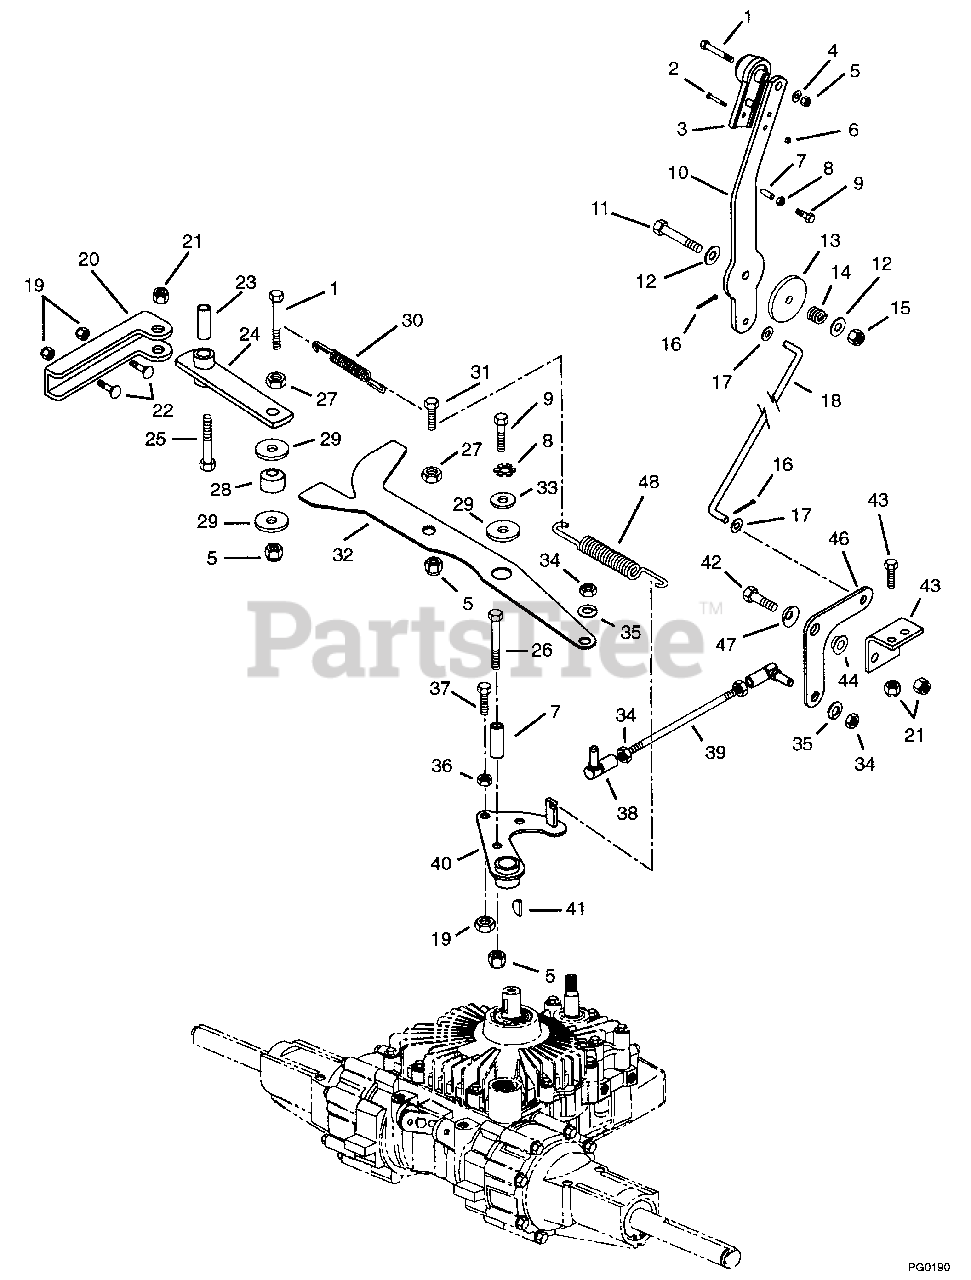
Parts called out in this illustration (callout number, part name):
1	Bolt-Hex .25-20 x 1.50 Grade 5
2	Screw-Machine 6-32 x .625
4	Washer-Flat-Steel .281 x .62 x .065
5	Nut-Locking-Nylon .250-20
6	Nut-Locking-Machine 6-32
7	Bushing-Sleeve .250 x .375 x .640
8	Washer-Lock External .313 x .030
9	Bolt-Hex .25-20 x .75 Grade 5
10	Lever, Speed Control
11	Bolt-Hex .50-13 x 2.50 Grade 5
12	Washer-Flat-Steel .531 x 1.062 x .095
13	Disc, Friction Material
14	Spring-Compression .125 x .78 x 1.00
15	Nut-Locking-Nylon .50-13
16	Pin-Cotter .09 x 1.00
17	Washer-Flat-Steel .406 x .812 x .065
18	Rod, Speed Control Lever
19	Nut-Locking-Nylon .375-16
20	Bracket, Roll Pivot
21	Nut-Locking-Nylon .312-18
22	Bolt-Round Head Square Neck .38-16 x .75
23	Bushing, Neutral Roller Lever
24	Pivot, Arm
25	Bolt-Hex .31-18 x 2.00 Grade 5
26	Bolt-Hex .25-20 x 1.25 Grade 5
27	Nut .250-20
28	Bearing Ball Double
29	Washer-Flat-Steel .281 x 1.250 x .062
30	Spring-Tension .051 x .60 x 2.25
31	Bolt-Hex .25-20 x 1.00 Grade 5
32	Transmission Arm, Detent
33	Washer-Flat-Steel .312 x .734 x .065
34	Nut - 5/16-24, Hex, Plated
35	Washer-Lock .312 x .097
36	Nut-Hex .375-16 Grade 2
37	Bolt-Hex .38-16 x 1.25 Grade 5
38	Ball Joint-Snap In
39	Rod, Speed Control Lower Link
40	Transmission Arm, Speed Interlock
41	Key, Woodruff .125 x .50 x .203
42	Bolt-Hex .31-18 x 1.00 Grade 5
43	Bolt-Hex .31-18 x .75 Grade 5
44	Bushing-Flange .312 x .500 x .344 x .880
45	Bracket, Speed Control Crank
46	Bell Crank, Mast Speed Control
47	Washer, Belleville Spring
48	Spring-Ten .085 x .750 x 3.50
